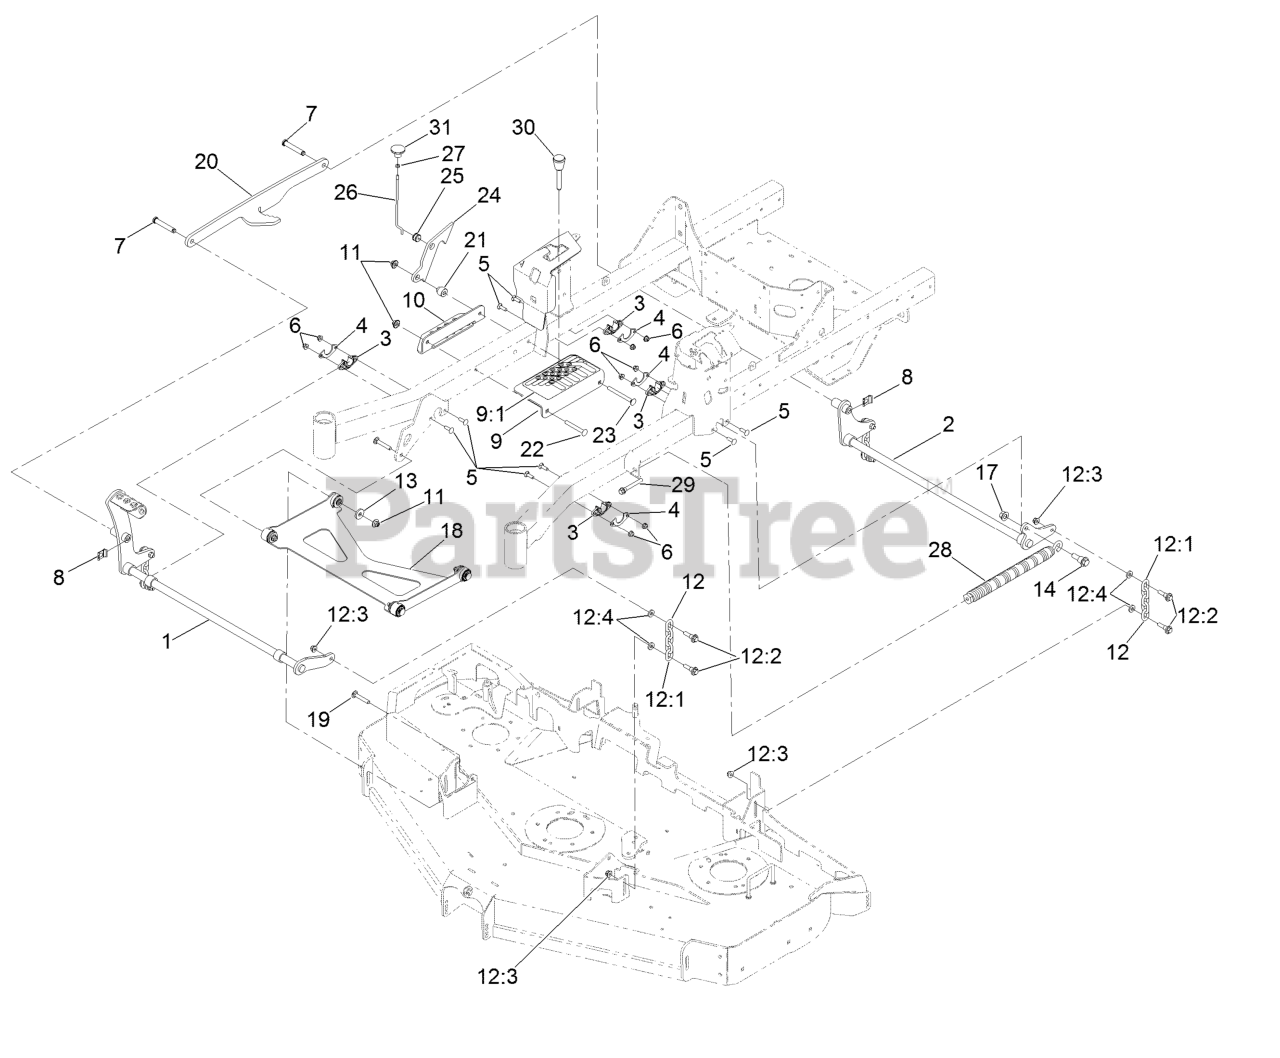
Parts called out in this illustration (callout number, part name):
1	Shaft-Lift, Deck
2	Shaft-Lift, Deck (Rear)
3	Bushing-Flange
4	Gusset-Lift, Deck
5	Screw-CARR
6	Nut-HF, NI
7	Pin-Clevis
8	Clip-Pin
9	Bracket ASM
9:1	Decal-HOC
10	Angle-HOC, Lower
11	Nut-Flange, NI
12	Deck Chain ASM
12:1	Chain-Lift, Deck
12:2	Bolt-Shoulder
12:3	Nut-HF, NI
14	Screw-Shoulder, HHF
17	Nut-Lock
18	Deck Strut ASM
19	Screw-CARR
20	Link-Lift
21	Spacer-Stepped
22	Screw-CARR
23	Screw-CARR
24	Plate-Lock, Transport
25	Grommet
26	Rod-Lock, Transport
27	Nut-Jam
28	Spring-Extension
29	Bolt-Shoulder
30	Pin-HOC
